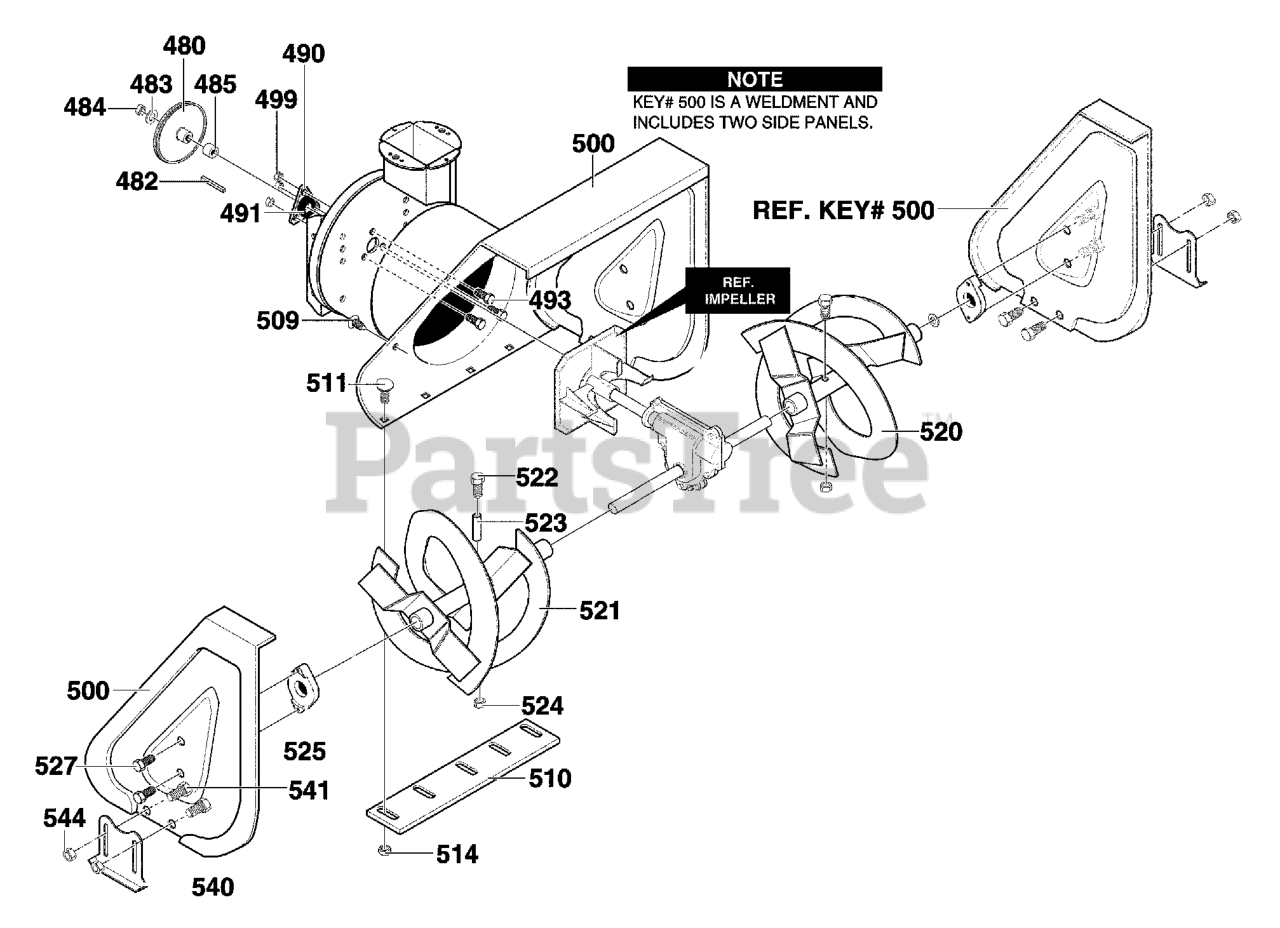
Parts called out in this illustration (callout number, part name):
480	PULLEY, V4L
482	KEY, SQUARE
483	WASHER, FLAT .53X1.00X.063
484	NUT, 1/2-20 REGHEXCTRLK
485	SPACER, SLEEVE
490	RETAINER, BALL
491	BEARING, BALL
493	SCREW, 5/16-18 x 0.75
499	NUT, 5/16-18
500	HOUSING, ASSY
509	PLUG, CHRISTMAS TREE
510	SCRAPER BLADE
511	BOLT, 1/4-20X.75 CARR.
514	NUT, 5/16-18 HEXWDFLLK WHIZ
520	AUGER, LH
521	AUGER, RH
522	SCREW, 1/4-20X1.75
523	SPACER, SLEEVE
524	NUT, 1/4-20 REGHXCTRLK
525	BEARING, AUGER SHAFT
527	SCREW, 5/16-18 x 0.75
540	SKID, HEIGHT ADJUST
541	BOLT, 5/16-18X .75
544	NUT, 5/16-18 REGHEX
